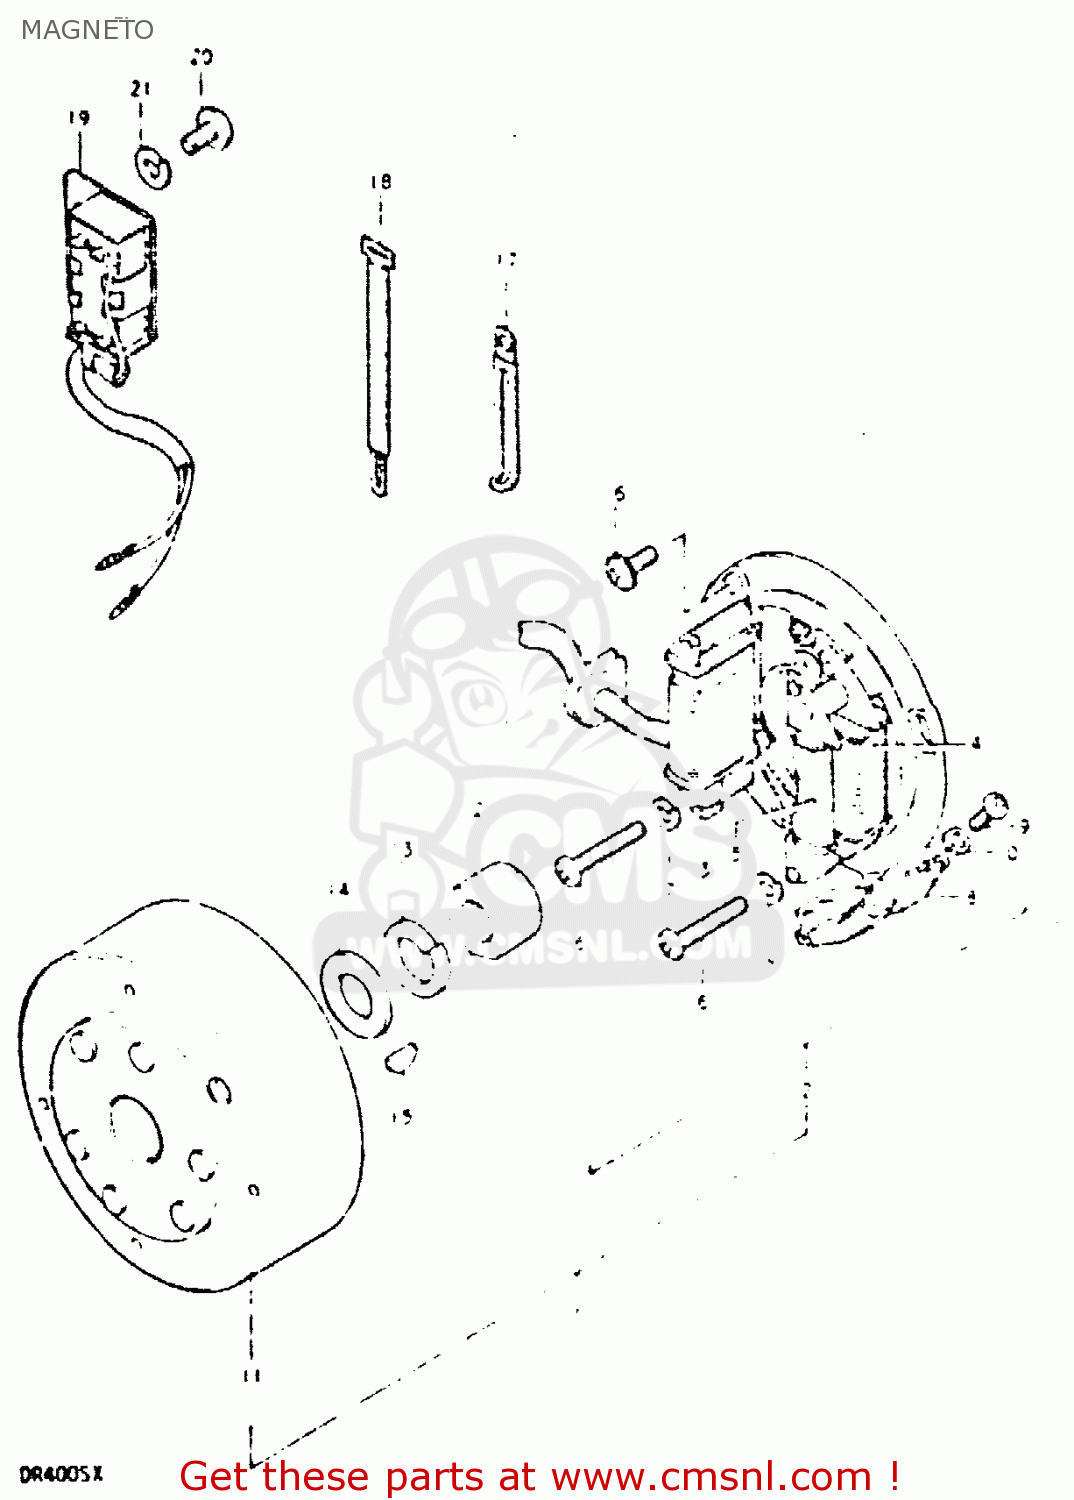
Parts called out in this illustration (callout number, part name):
1	MAGNETO ASSEMBLY
2	STARTER ASSY
3	COIL,LIGHTING
4	COIL,PRIMARY
5	COIL,PULSER
6	SCREW
7	LOCK WASHER
8	COIL,PULSER
9	SCREW
10	LOCK WASHER
11	ROTOR,FLYWHEEL
12	NUT
13	LOCK WASHER
14	WASHER(14X27X3)
15	KEY 4MM
16	SCREW(5X14)
17	CLAMP
18	CLAMP L:110
19	REGISTER ASSEMBLY
20	SCREW 6X12
21	LOCK WASHER
